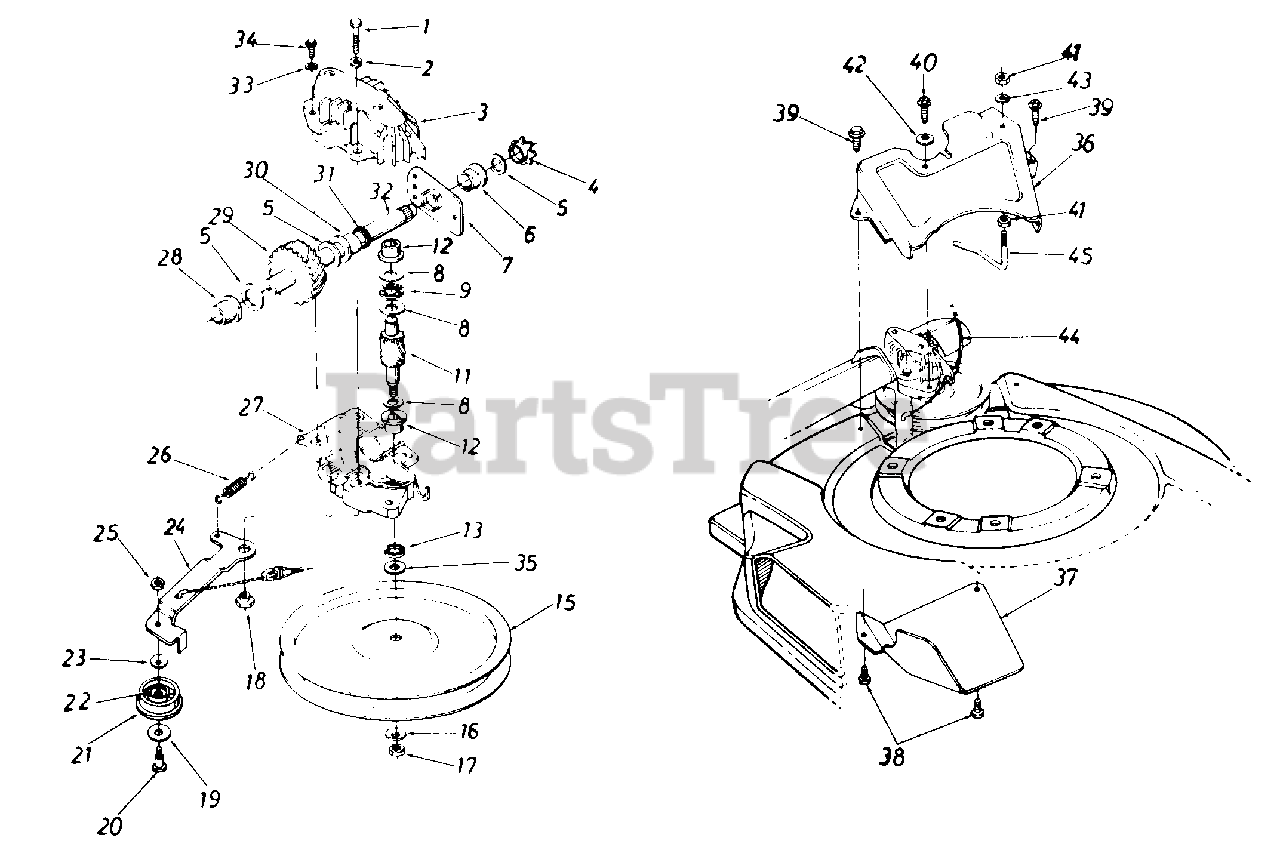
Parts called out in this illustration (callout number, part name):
1	Hex Bolt 1/4-20 x 1.25" Lg.
2	L-Wash. 1/4" I.D.
3	Upper Hsg. Half
4	#48 Sprocket 7 Tooth x 1/2 Pitch
5	Fl-Wash. 5/8" I.D. x .030
6	Hex Flange Brg..631" I.D.
8	Thrust Wash..382" I.D. x .70" O.D.
9	Thrust Bearing .375" I.D. x .812" O.D.
11	11 Tooth Helical Gear
12	Flange Bearing
13	Oil Seal
15	Fl-Pulley 5.06" I.D.
16	Bell-Wash..265" I.D. x .75"
17	Hex Nut 1/4-28 L.H. Thd.
18	Shld. Spacer .375" Dia. x .170"
20	Shld. Bolt .375" Dia. x .40"
21	Fl-Idler Plastic 1.50" Dia.
22	Needle Brg..375" x .375"
23	Bell-Wash..265" I.D. x .75"
24	Idler Brk't. Ass'y.
25	Hex Patch L-Nut 1/4-28 Thd.
26	Extension Spring 1.12" Lg.
27	Lower Hsg. Half
28	Flange Bearing .56 Dia.
29	33 Tooth Helical Gear
30	Flange Bearing .629 Dia.
31	Oil Seal .625 Dia.
32	Gear Sprocket Shaft
33	L-Wash. #10 I.D.
34	Hex B-Tap Scr. #10 x .62"
35	Hex Washer .26" x .88"
39	Hex AB-Tap Scr. 1/4 x .50" Lg.
40	Hex B-Tap Scr. 1/4 x .62" Lg.
41	Hex Nut 1/4-20 Thd.
42	Bell-Wash..265" I.D. x .75"
43	L-Wash. 1/4" I.D.
44	S.P. Cable - 48" Lg.
45	S.P. Belt Guard
